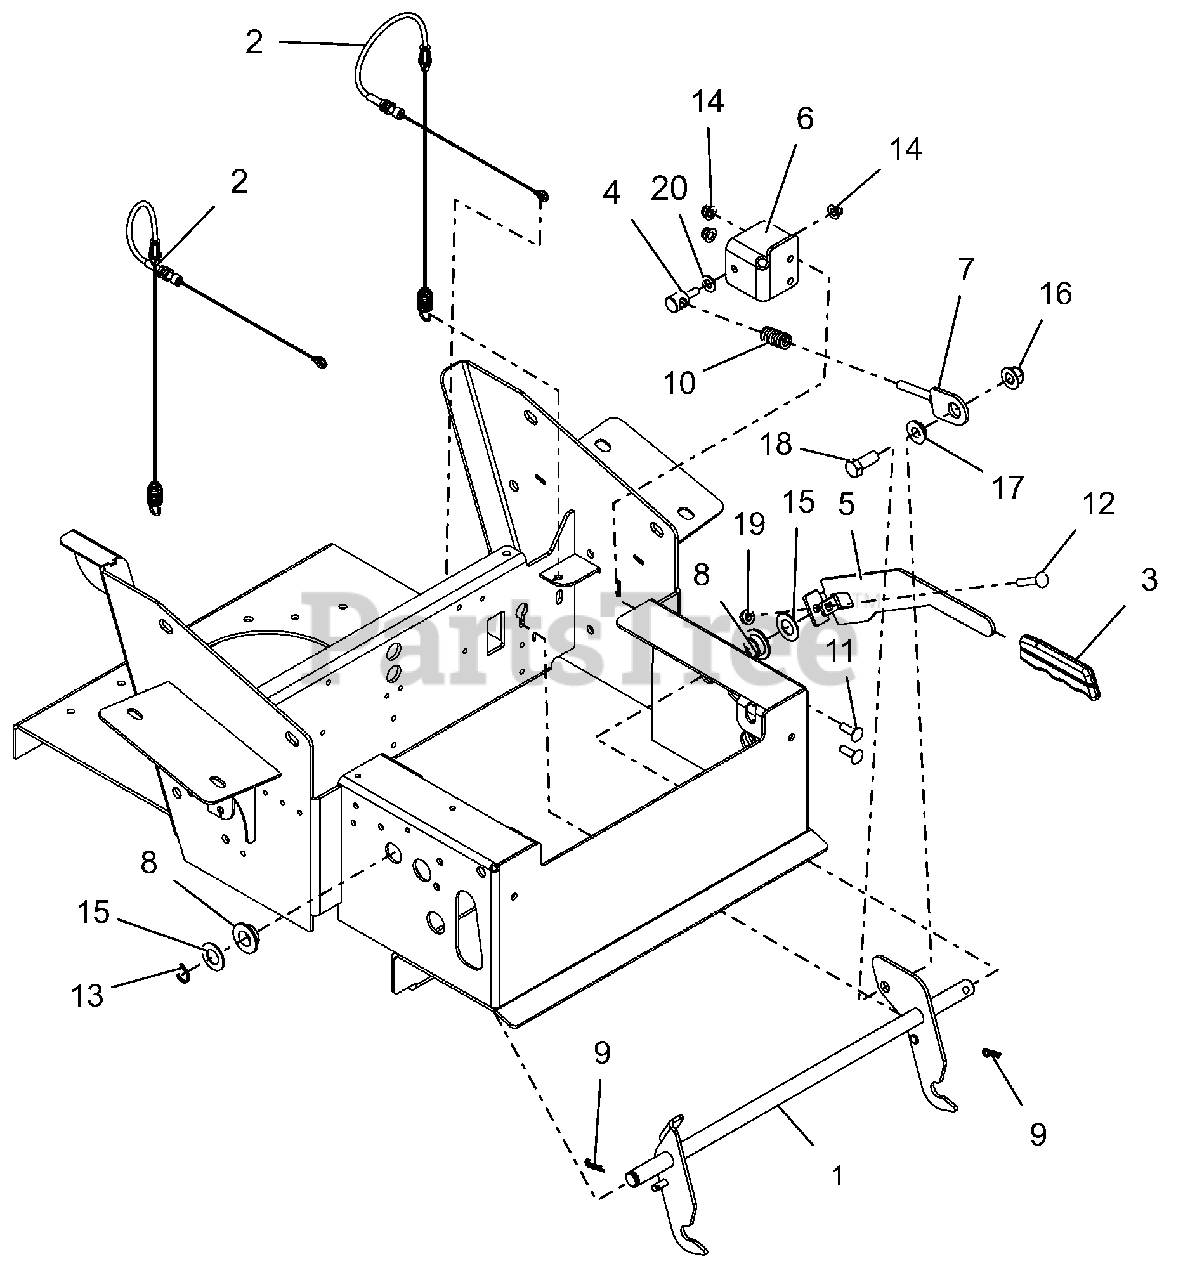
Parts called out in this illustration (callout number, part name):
1	PT/PT100 BRAKE LEVER WMT-LOW F
2	CABLE, BRAKE ACCUATING
3	GRIP, PARKING BRAKE (YELLOW)
4	.38-16 TRUNNION - LOW FILM
5	PT/PT100 BRAKE HANDLE - BLK
6	TRUNNION MTG BRACKET - BLACK
7	WLDMT, BRAKE SPRING MOUNTING
8	BSHG-FLG .762X1.48X.44 NYL
9	PIN-HAIR INT .08X.18X1.18 YWZC
10	SG-COMP .142 X .710 X 1.75
11	@BLT-RDHDSQNK .31-18X1.00 G5YZ
12	@BLT-RDHDSQNK .31-18X1.75 G5YZ
13	RG-RTNG-EXT .689X.078
14	@NUT-LK-NYL-FLG .31-18 YWZC
15	WSHR-FL-STL.755X1.375X.062YWZC
16	@NUT-LK-NYL-FLG .50-13 YWZC
17	BSHG-FLG .515X.750X.310X1.120
18	@BLT-HEX .50-13X1.25 GR5 YWZC
19	@NUT-LK-CTR-FLG .31-18 YZ GR F
20	@WSHR-FL-STL.406X.812X.065 YWZ
